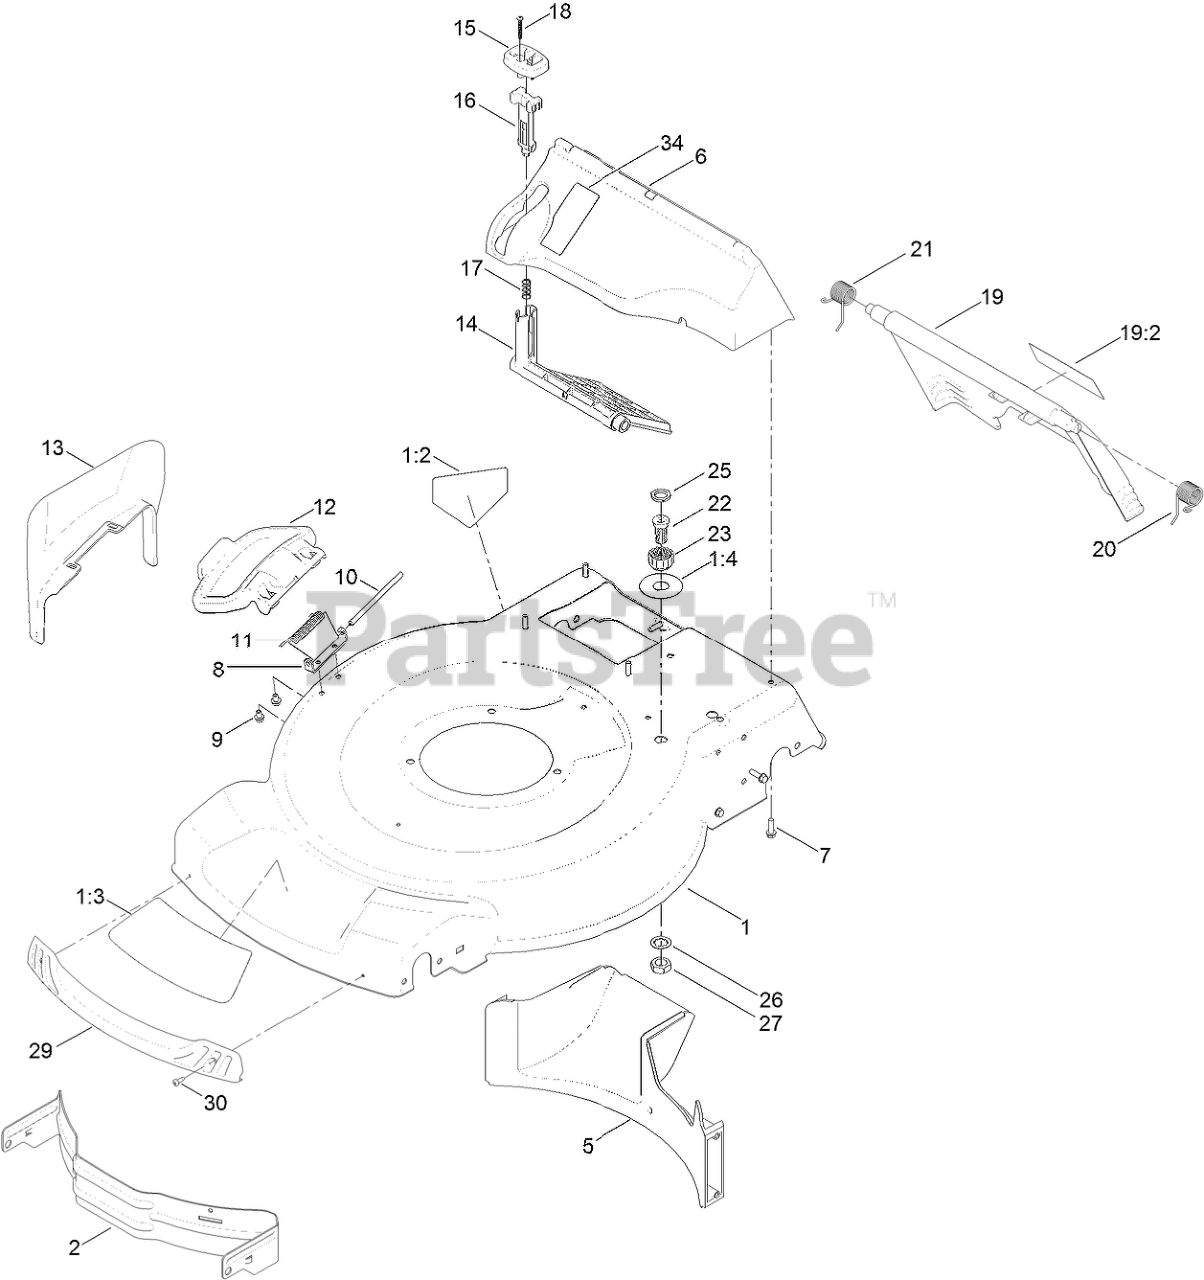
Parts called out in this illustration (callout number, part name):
1	HOUSING ASM
1:2	DECAL-DANGER
1:3	DECAL-RECYCLER
1:4	DECAL-PORT, WASHOUT
2	BAFFLE-FRONT
5	BAFFLE-REAR
6	CHUTE-RECYCLE
7	SCREW-HWH
8	BRACKET-COVER
9	SCREW-HWH
10	ROD-COVER
11	SPRING-TORSION
12	DEFLECTOR-SIDE
13	CHUTE-DISCHARGE, SIDE
14	DEFLECTOR-RECYCLE
15	KNOB-RECYCLE
16	LATCH-RECYCLE
17	SPRING-COMPRESSION
18	SCREW-PPH
19	REAR DOOR ASM
19:2	DECAL-WARNING
20	SPRING-TORSION
21	SPRING-TORSION
22	PORT-WASHOUT
23	COUPLING-HOSE, WASHOUT PORT
25	WASHER-SEAL, WASHOUT PORT
26	WASHER-TOOTH, INTERNAL
27	NUT-JAM
29	BUMPER
30	SCREW-FORMING, THREAD
